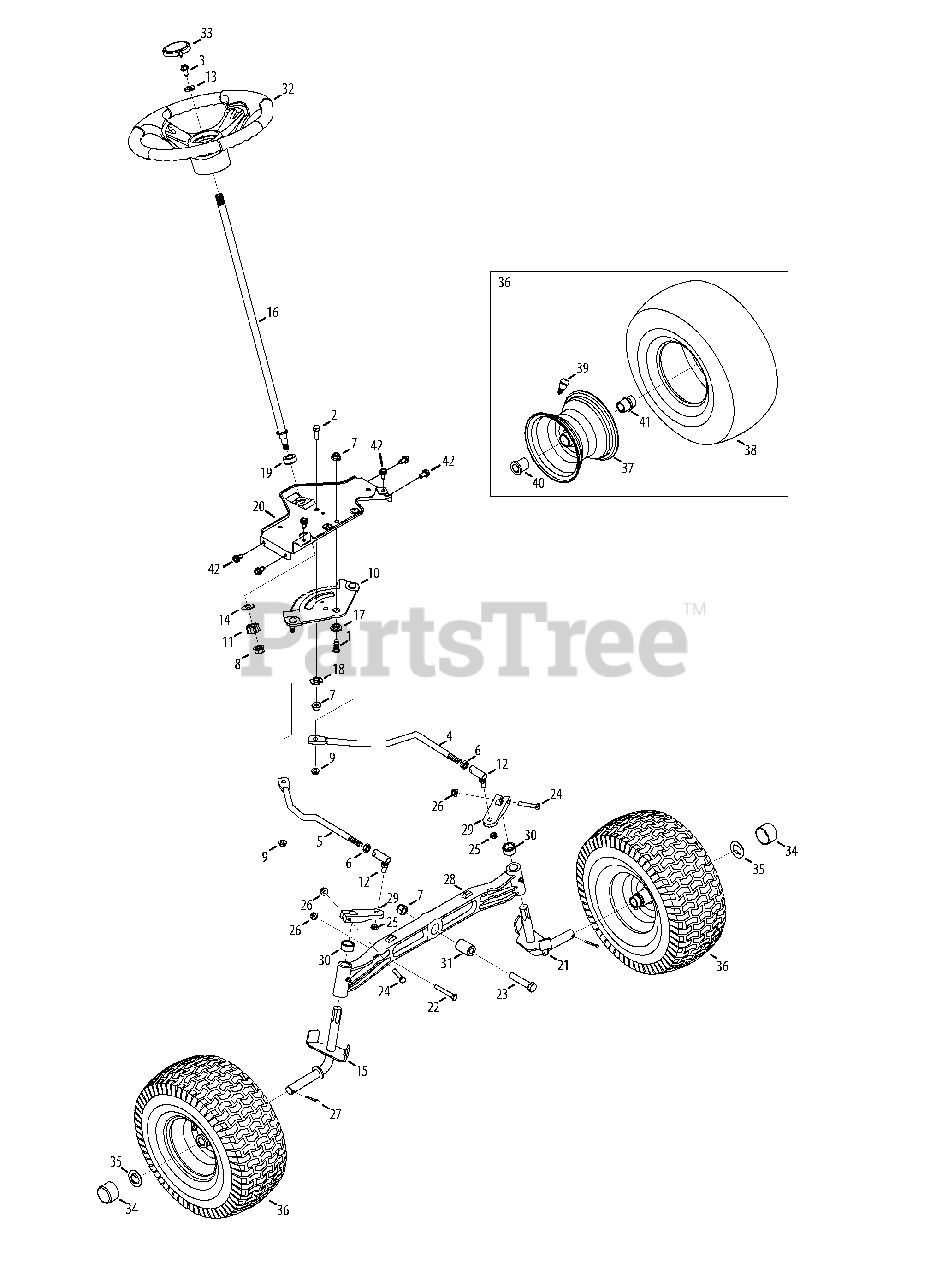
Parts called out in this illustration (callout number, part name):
1	Hex Head Screw, 3/8-16:1.00
2	Hex Head Screw, 3/8-16:1.00
3	Hex Head Screw, 5/16-18:1.00
4	LH Drag Link
5	RH Drag Link
6	Jam Nut, 7/16-20
7	Flangelock Nut, 3/8-16
8	Flangelock Nut, 7/16-20
9	Flangelock Nut, 5/16-18
10	Steering Gear
11	Steering Pinion Gear
12	Ball Joint, 7/16-20
13	Flat Washer, .406 x .875 x .105
14	Flat Washer, .51 x 1.12 x .06:HT
15	RH Axle Assembly
16	Steering Shaft, .625 OD x 24.25 LG
17	Shoulder Spacer, .385X 1.25 x .3025
18	Spacer, .38 x 1.375
19	Hex Flange Bearing 5/8 PM
20	Steering Support Bracket
21	LH Axle Assembly
22	Hex Head Screw, 5/16-18:2.25
23	Hex Head Screw, 3/8-16:2.50
24	Hex Head Screw, 5/16-18:1.75
25	Hexlock Nut, 3/8-24
26	Flangelock Nut, 5/16-18
27	Cotter Pin, 5/32:1.25
28	Pivot Bar Axle
29	Steering Block
30	Spacer, .71 ID x .125 OD x .56LG
31	Spacer, .385 x 1.00 x 1.5075
32	Steering Wheel, Soft Grip
33	Cap, Troy-Bilt
34	Bumper Cap
35	Flat Washer, .781ID x 1.590OD
36	Wheel Assembly
37	Rim Assembly
39	Tubeless Air Valve
40	Flange Bearing, .760 x 1.00 x 1.20LG
41	Flange Bearing, .760ID
42	Screw, Self-tapping, 5/16-18, .750,
